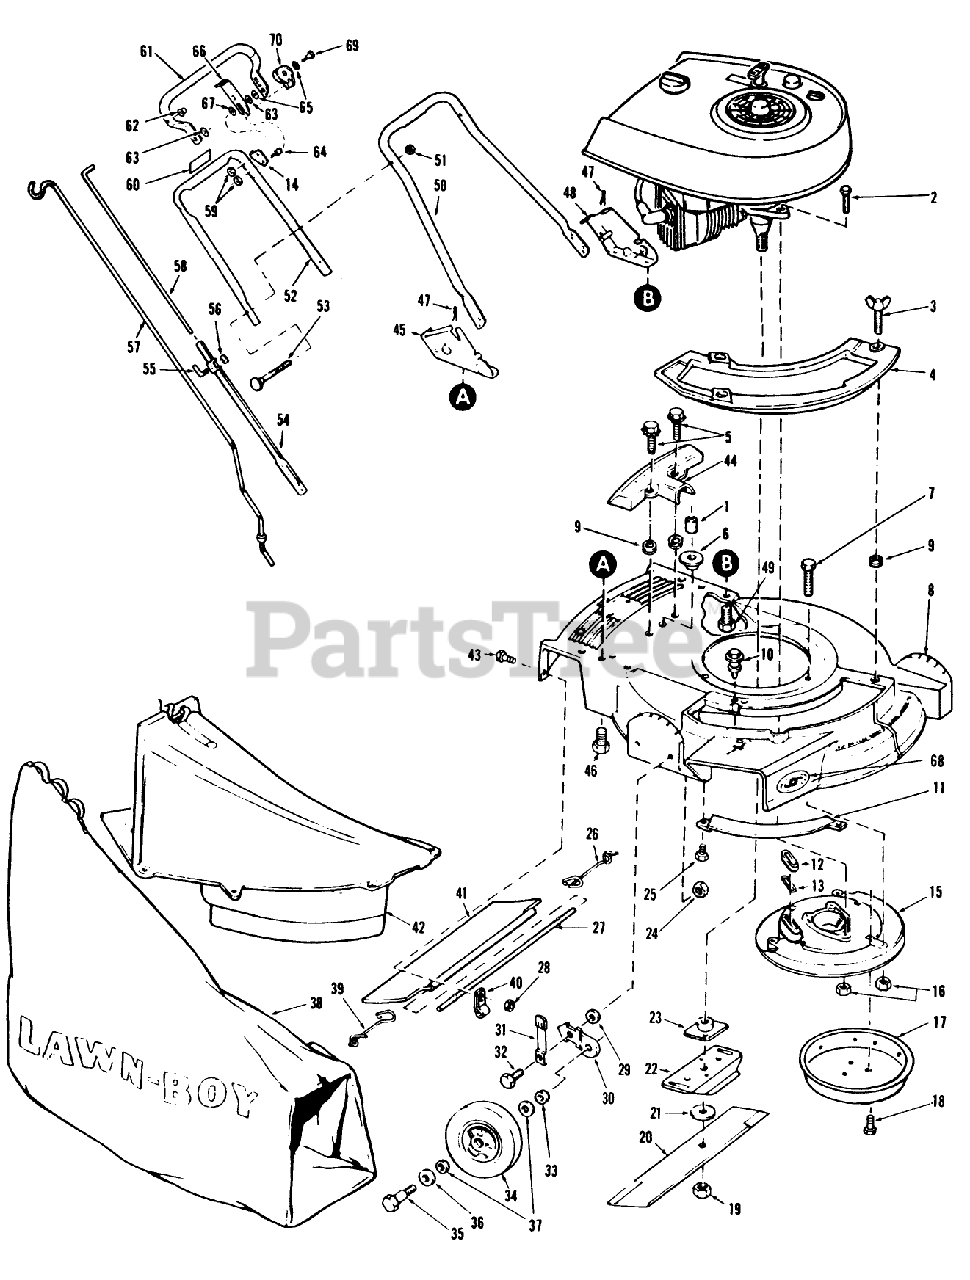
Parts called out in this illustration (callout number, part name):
3	WING SCREW LAWRE
5	SCREW SEMS TRM HEX HD
6	SPACER ECK PRES
7	SCREW V
11	BAR-TOE
13	GASKET S
14	HANDLE STOP
16	NUT-LOCK F
19	NUT-BLADE
23	PLATE AND COLLAR ASM
24	NUT-LOCK F
26	SPRIG T/SHLD ASOC
27	ROD 21" ADVANCE
28	LOCKNUT E
33	WASHER WROUGHT
35	BOLT WHEEL
39	SPRING;TRAILING SHIELD RH
40	CLAMP ROD KMC
45	HANDLE BRACKET
47	HAIR PIN
50	Cover Plate
51	LOCKNUT E
57	ROD GRASSBAG
58	ROD CONTROL
59	LOCKNUT E
61	Handle Grip Assy.
63	WASHER M
64	SCREW-HANDLE STOP
69	BOLT PIONEER
